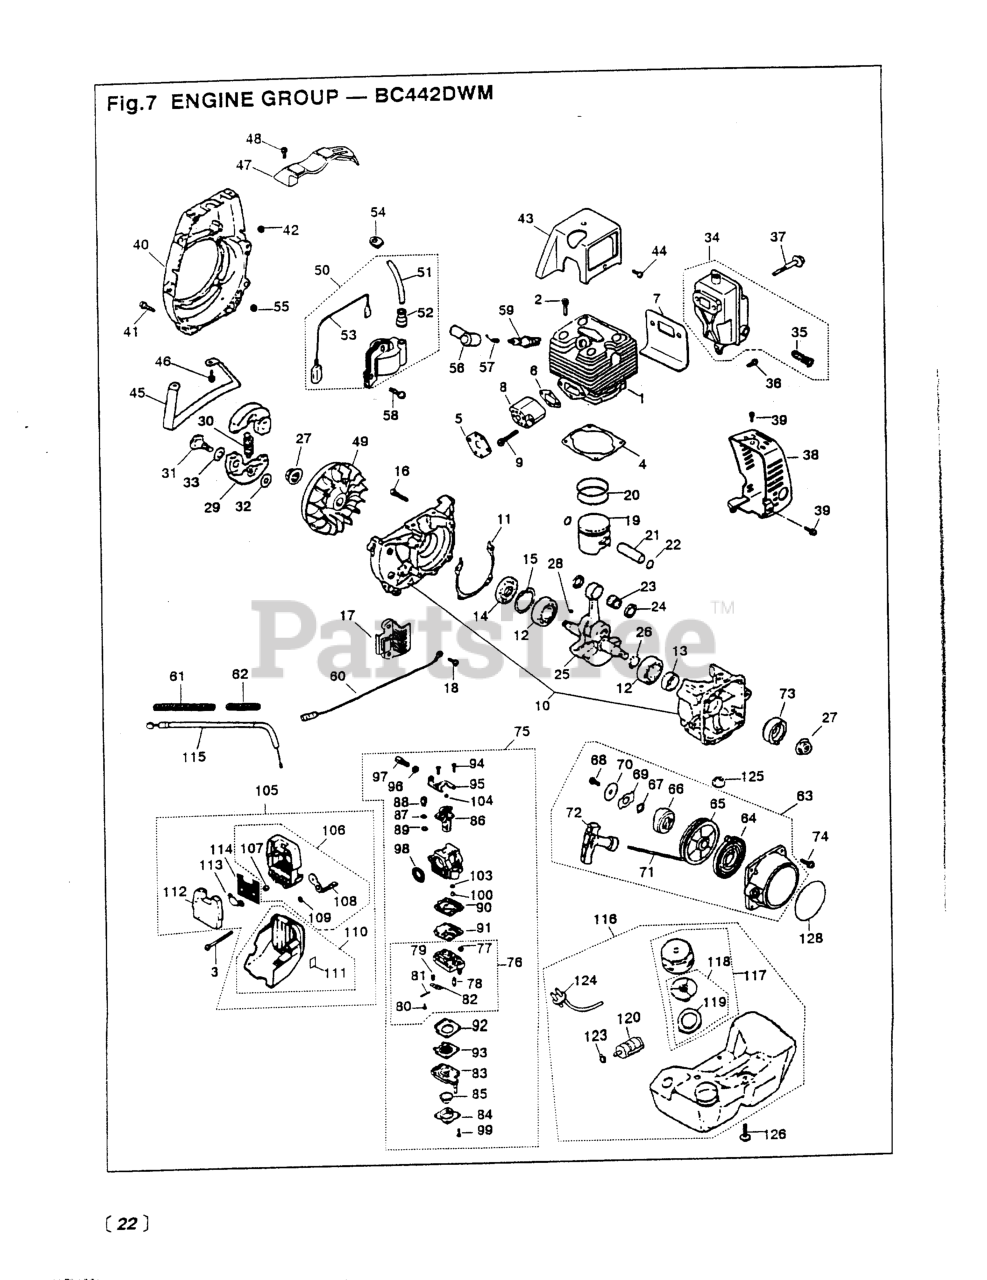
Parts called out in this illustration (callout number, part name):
2	BOLT M5 x 20 (RPLS -12280)
8	INSULATOR (RPLS -13162)
9	SCREW, M5 X 40
10	CRANKCASE COMPLETE
13	SEAL, OIL - STARTER SIDE
15	RING, SNAP, M35 X 1.5
16	BOLT, M5 X 30
17	GUARD (RPLS-21310)
18	SCREW,M5 X 14 (RPLS 1400-15510
19	PISTON
20	RING
21	PIN, PISTON
22	RING, SNAP
23	BEARING
24	WASHER (RPLS 1491-41510)
25	SHAFT (RPLS -42001)
26	SHIM (REPLACES 848-870-G000)
27	NUT, M10
28	KEY
31	SCREW
32	WASHER
33	WASHER (USE -51241)
35	ARRESTER
36	SCREW, M5 X 12
37	BOLT
38	COVER
39	SCREW, M5 X 12
40	COVER, FAN (REPLACES -31111)
41	BOLT M5 x 20 (RPLS -12280)
43	COVER (RPLS -32110)
44	SCREW, M5 X 12
45	STAND
46	BOLT (REPLACES 01252-30514)
48	SCREW, M5X20 (RPLS.1400-75510)
50	COIL ASSEMBLY
52	CAP
54	GROMMET
57	SPRING
58	SCREW, M5X20 (RPLS.1400-75510)
62	TUBE (RPLS -72930)
64	SPRING (RPLS -75220)
66	DOG
67	WASHER
68	SCREW
69	RETAINER (RPLS 1861-75161)
70	WASHER
71	ROPE
72	KNOB
73	PULLEY (RPLS -75210)
74	SCREW, M5X20 (RPLS.1400-75510)
75	CARBURETOR ASSEMBLY
76	BODY, PUMP
78	VALVE, INLET
79	SPRING, METERING LEVER
80	SCREW, METERING LEVER PIN
81	PIN, METERING LEVER
82	LEVER
83	BODY, PURGE
84	COVER, PUMP
85	PUMP, PRIMING
87	WASHER
88	SWIVEL
89	RING
90	GASKET, PUMP
91	DIAPHRAGM
92	GASKET, DIAPHRAGM
93	DIAPHRAGM (USE 4810-81260)
94	SCREW
96	NUT, CABLE ADJUSTER
98	RING, PACKING
99	SCREW
103	RING, O
107	SLEEVE
110	COVER, AIR FILTER (RPLS -82201
111	LABEL
113	PLATE
115	CABLE COMPLETE
118	VALVE COMPLETE
119	PACKING (RPLS -85321)
120	FILTER ASSY
123	CLIP (REPLACES 2841-31280)
124	PIPE ASSY (RPLS -85800)
126	SCREW
128	LABEL, RECOIL(RPLS 1403-75411)
